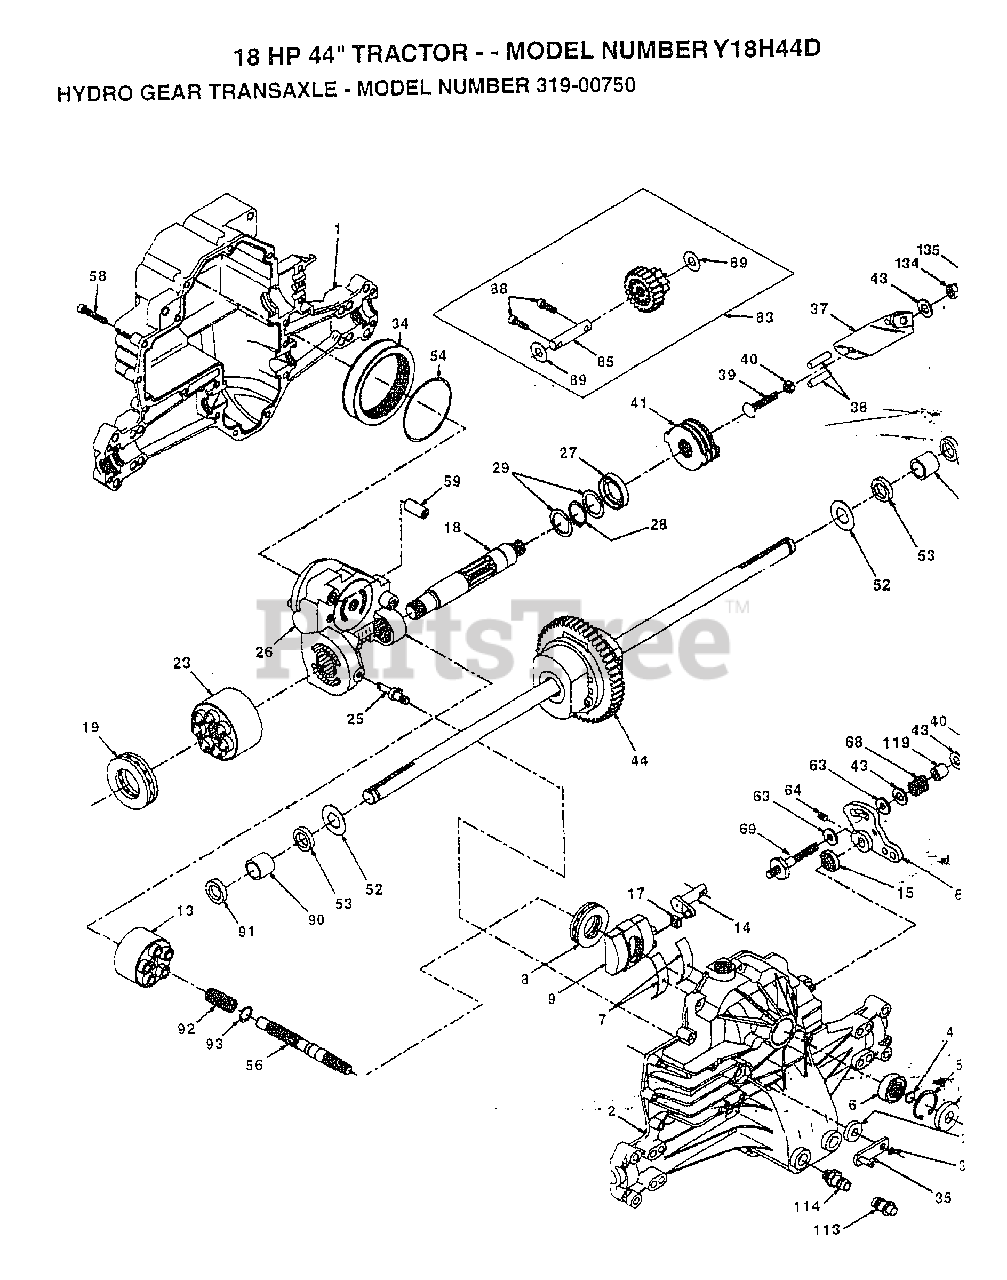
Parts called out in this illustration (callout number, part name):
1	HOUSING.L.50074RM
2	HOUSING.UP.70125
3	SEAL.9008000-0128
4	RING.RET.2003016.
5	RING.RET.2003052.
6	BEARING.(50552)42X68X16
7	CRADLE- 2003023.
8	BEARING.2003044.
9	SWASHPLT.2003087.
13	BLOCK.CLYN.70079.
14	ARM.TRUN.2003005.
15	SEAL.9008000-0126
17	GUIDE.2000015.
18	SHAFT.MOTOR.50115
19	BEARING.THS.50019
23	BLOCK.CYLIN.70082
24	SEAL.LIP.45074
25	ACTUATOR.2003555
26	KIT.CENTER.70133
27	SEAL.LIP.45075
28	RING RETAIN 50007
29	WASHER.44872
34	ELEMENT.OIL.44964
35	ARM.BYPASS.50270
36	RING.RETAIN.44870
37	ARM.ACTUAT.23710
38	PIN.ACTUAT.44891
40	NUT.LOCK.HX.50108
41	KIT.BRAKE.70135
43	WASHER HYD 44130
44	DIFFERENTIA.70130
52	WASHER.HYD.50152
53	SEAL.HYDRO.45076
54	O RING.HYD.45077
56	SHAFT.INPUT.50005
58	BOLT.1/4-20.44876
59	PIN.HYDRO.50002
62	ARM.CONTROL.50254
63	PUCK.DAMPER.50281
64	SCREW.SET.50018.
68	SPRING.HYD.50277
69	STUD.5/16-24.DANA
83	JACKSHAFT/PINION GEAR.70132
85	JACKSHAFT.50086
88	SCREW.CAP.50154.
89	WASHER.HYD.50132
90	BEARING.SLV.50118
91	SEAL.WIPER.50941
92	SPRING.2003014.
93	WASHER.2003017
113	CAP.VENT.70109
114	O-RING.ASM.70110
119	SPACER.HYD.50278
134	NUT.CAS.HYD.44142
135	PIN.COT.HYD.44101
